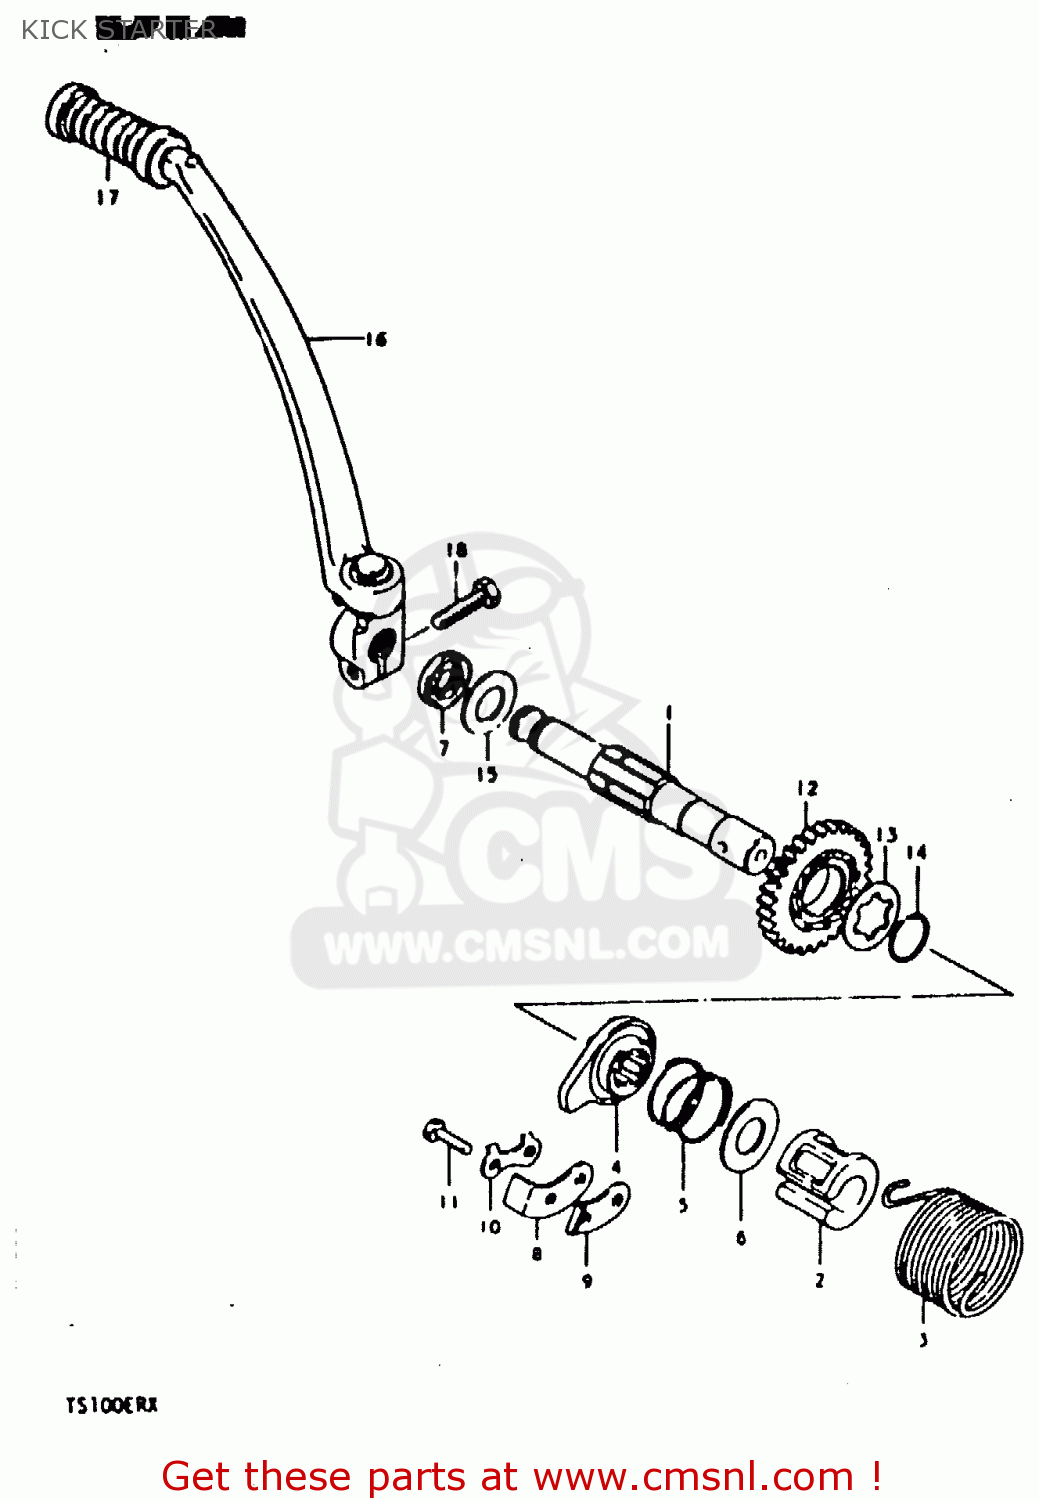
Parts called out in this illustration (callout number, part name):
1	SHAFT,KICK STARTER
2	GUIDE,KICK STARTER SFT SPRING
3	SPRING
4	STARTER,KICK
5	SPRING
6	WASHER
7	SEAL,OIL(16X30X8)
8	GUIDE,KICK STARTER
9	STOPPER,KICK STARTER
10	WASHER
11	BOLT, UPPER
12	GEAR,KICK STARTER DRIVE
13	WASHER,LOCK
14	CIRCLIP
15	WASHER(16X30X1)
16	LEVER ASSEMBLY,KICK STARTER
17	COVER
18	BOLT
